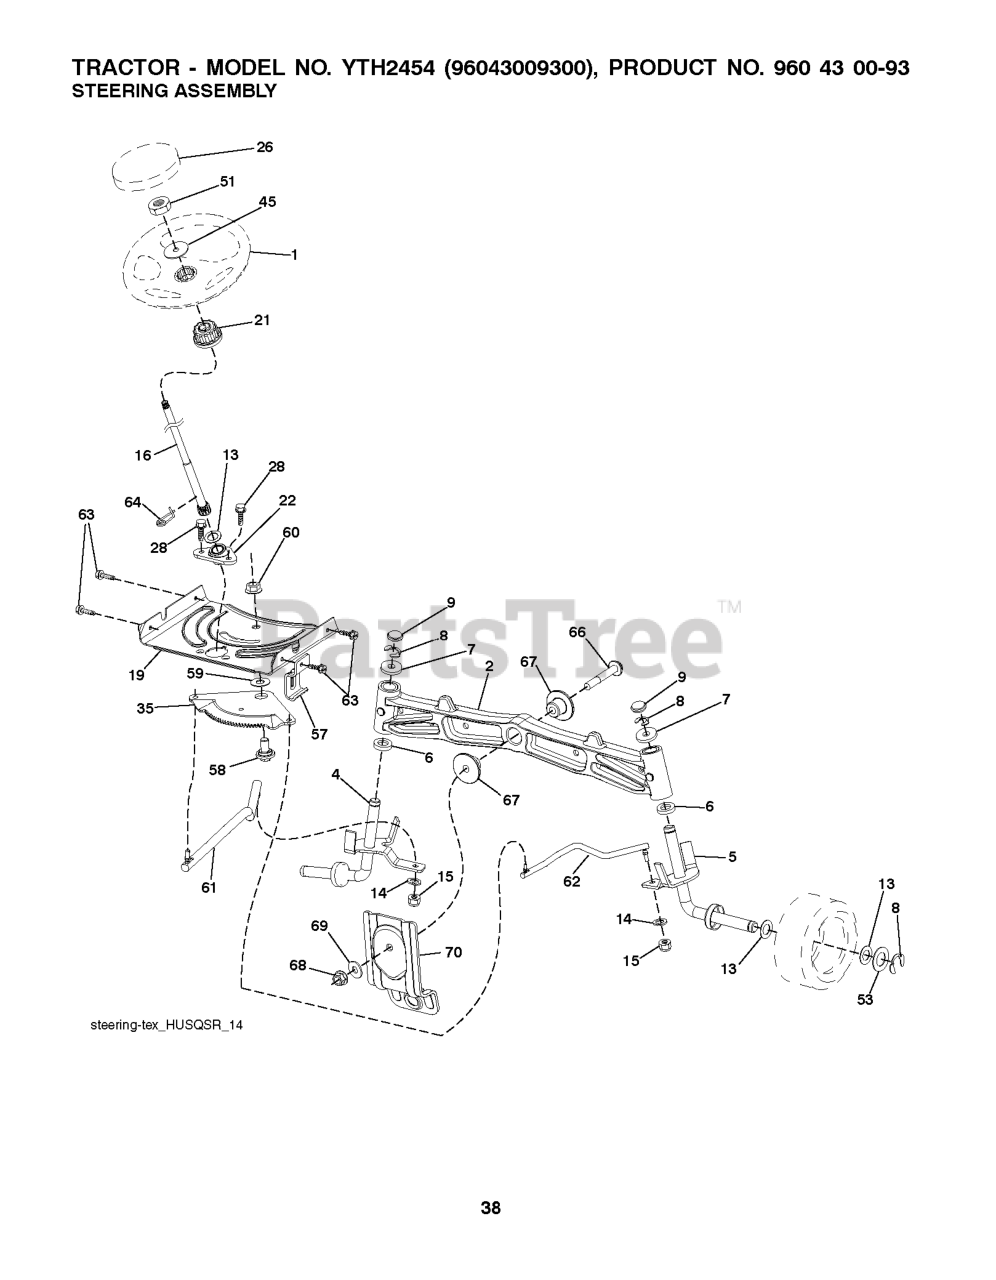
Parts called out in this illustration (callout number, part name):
1	RP WHEEL.STEER.HUSQ.PREM.OVMLD
2	AXLE.CAST.IRON
4	SPINDLE.WELDED.LH.16"TEX
5	SPINDLE.WELDED.RH.16"TEX
6	THRUST WASHER
9	CAP.SPINDLE.BLACK
14	WASHER, LOCK 3/8
15	NUT CROWNLOCK 3/8-24
16	SHAFT, STEERING
19	PLATE.STEER.DDL.NLT/NG
21	ADAPTER, WHEEL STNG..
22	STEERING.SUPT.LOWER.
26	RP INSERT.CAP.WHL.STRG.HUSQ.
28	SCREW, 3/8-16X3/4
35	GEAR.SECTOR.PLATE.DDL.
45	WASHER 9/16"ID, 2 3/8"OD
51	NUT.HEX.1/2-20
53	WASHER.HARDENED
57	BRKT.UPSTOP.GT/LT.TEX
58	BOLT.SHOULDER.SECTOR.P
59	WASHER.THURST.SECTOR.S
60	NUT FLANGE LOCK 5/8-11
61	DRAGLINK.LH.BALLSTUD.D
62	DRAGLINK.RH.BALLSTUD.D
63	SCREW
64	RETAINER.CLIP.SPRING.S
66	BOLT HEX FGHD 7/16-14 X 3 SERR
67	BUSHING.PM.FRONT AXLE
68	NUT.LOCK.FLANGE.7/16
69	WASHER.1.5X.505X.118
70	BRKT.DECK.SUSPENSION.F
